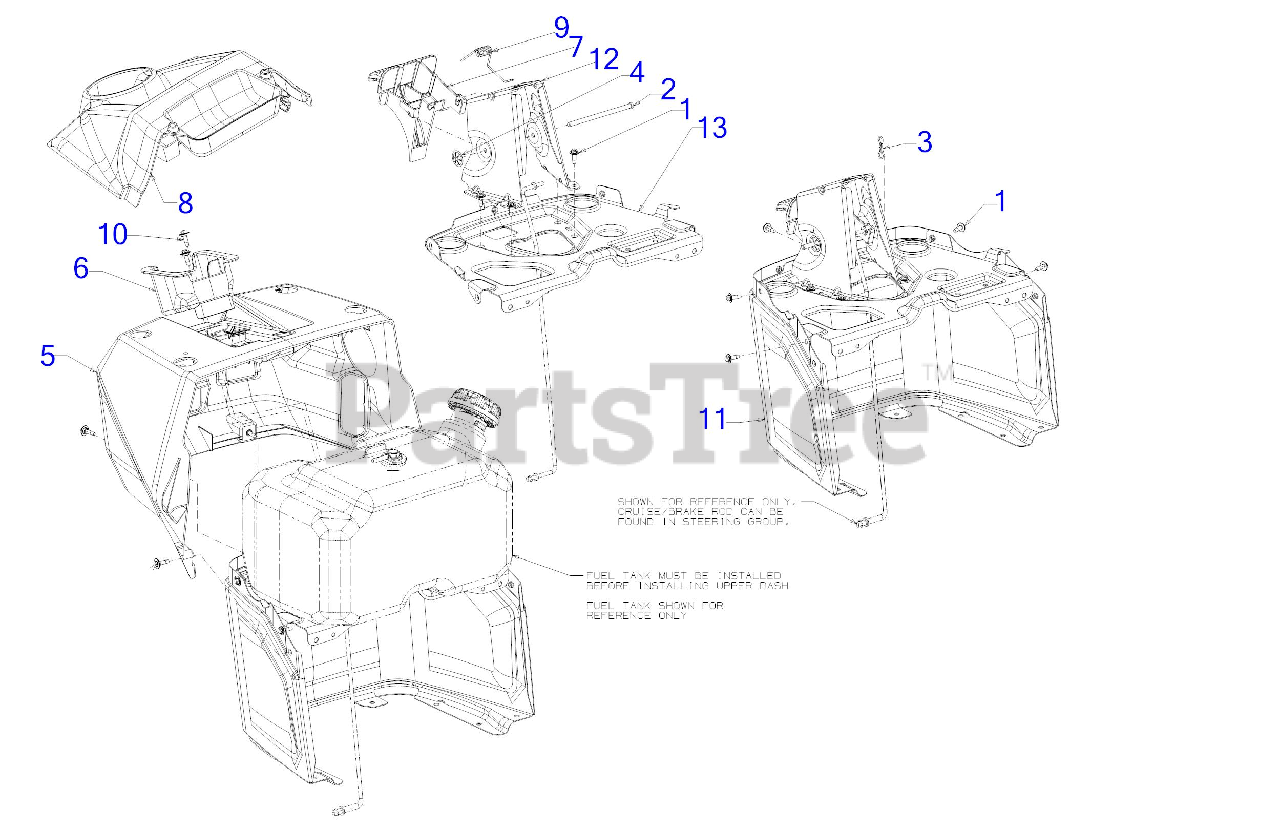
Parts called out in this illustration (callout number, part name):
1	SCREW M6-1 x .625
2	HINGE PIN .25 x 4.50
3	BOW TIE COTTER PIN 1/4-5/16
4	PUSH ON NUT
6	STEERING SHAFT BEARING
7	CRUISE/BRAKE DASH LEVER
8	UPPER DASH CAP
9	TORSION SPRING .330 ID
10	SHOULDER SCREW M6-1 .368 X.115
